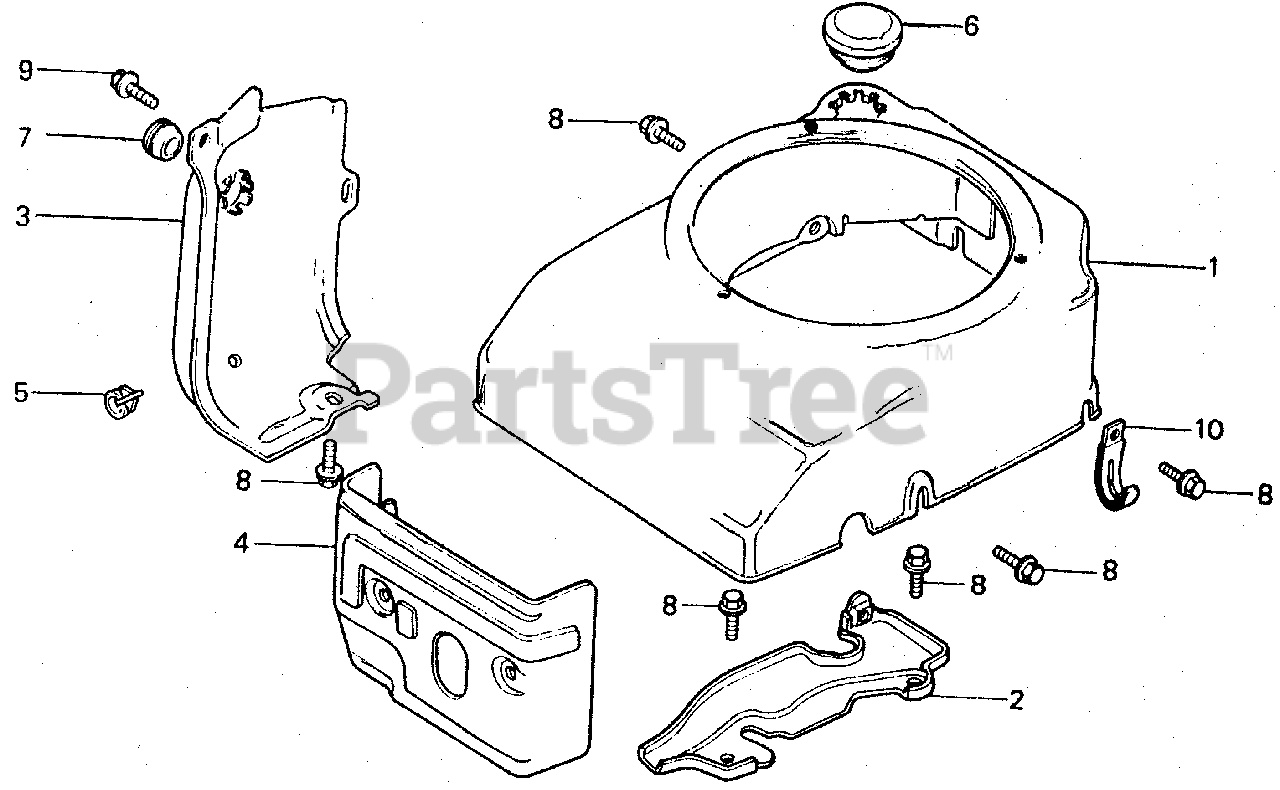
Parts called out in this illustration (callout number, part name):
1	COVER, FAN *R8* (BRIGHT RED)
2	PLATE, SIDE
3	SHROUD
4	COVER, TOP
5	CLIP, IGNITION WIRE (8MM)
6	GROMMET B, SIDE PANEL
7	GROMMET, DRAIN HOLE
8	BOLT, FLANGE (6X12) (CT200)
9	BOLT, FLANGE (6X14)
10	CLIP, CABLE
